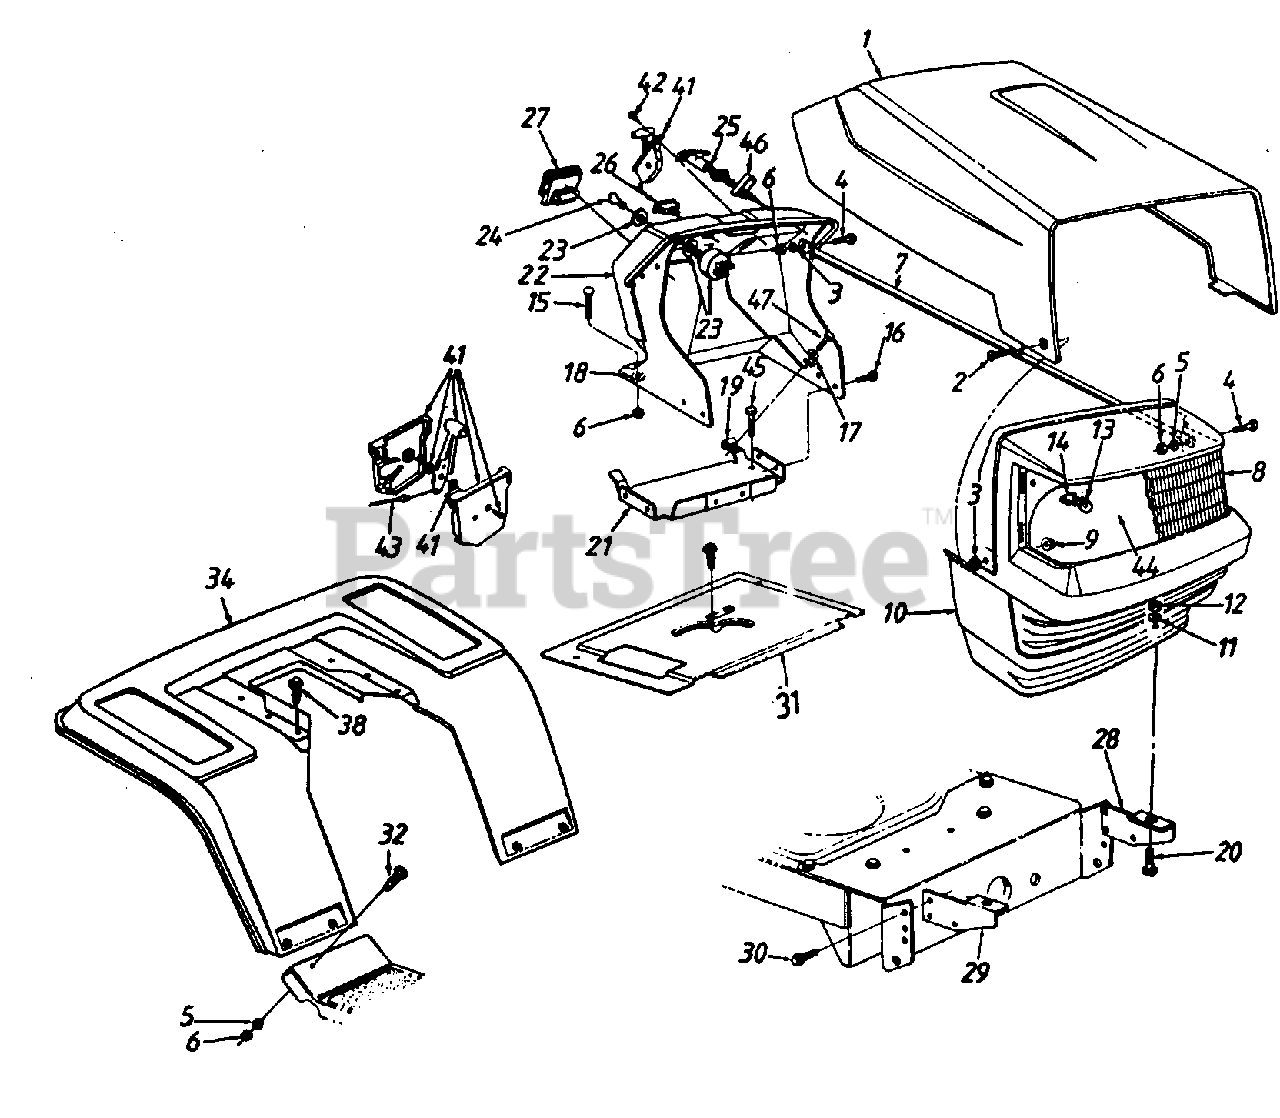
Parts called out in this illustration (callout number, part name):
1	Hood
2	Shld. Bolt .375" Dia. x .125" Lg.
3	Fl-Wash. .28" I.D. x .75" O.D.
4	Hex Bolt 1/4-20 x .62" Lg.
5	L-Wash. 1/4" I.D.
6	Hex Nut 1/4-20 Thd.
8	Headlight Lens
9	Flange L-Nut 1/4-28 Thd.
10	Grille
11	L-Wash. 5/16" I.D.
12	Hex Nut 5/16-18 Thd.
13	Lamp
14	Socket
15	Carriage Bolt 1/4-20 x .75" Lg.
16	Hex Wash. Hd. TT-Tap Scr. 1/4-20 x .5" Lg.
17	Fl-Wash. .281" I.D. x .73" O.D.
18	Bolt Retainer 1/4" I.D.
19	Speed Nut 1/4-20 Thd.
20	Hex Bolt 5/16-18 x .75" Lg.
21	Gas Tank Support Brkt.
22	Dash
23	Ignition Switch
24	Ignltion Key
25	Choke Control 20" Lg.
26	Light Switch
27	Ammeter
28	Grille Mtg. Brkt.-L.H.
31	Shift Cover
32	Truss Mach. Scr. 1/4-20 x .5" Lg.
41	Throttle Box Ass'y.
42	Truss Mach. AB-Tap Scr. #10 x .5" Lg.
43	Throttle Control Wire
44	Grille Reflector Label
45	Hex Wash. Hd. B-Tap Scr. 5/16-18 x .5" Lg.
46	Choke Retainer
47	Hex TT-Tap Scr. 1/4-20 x .75" Lg.
